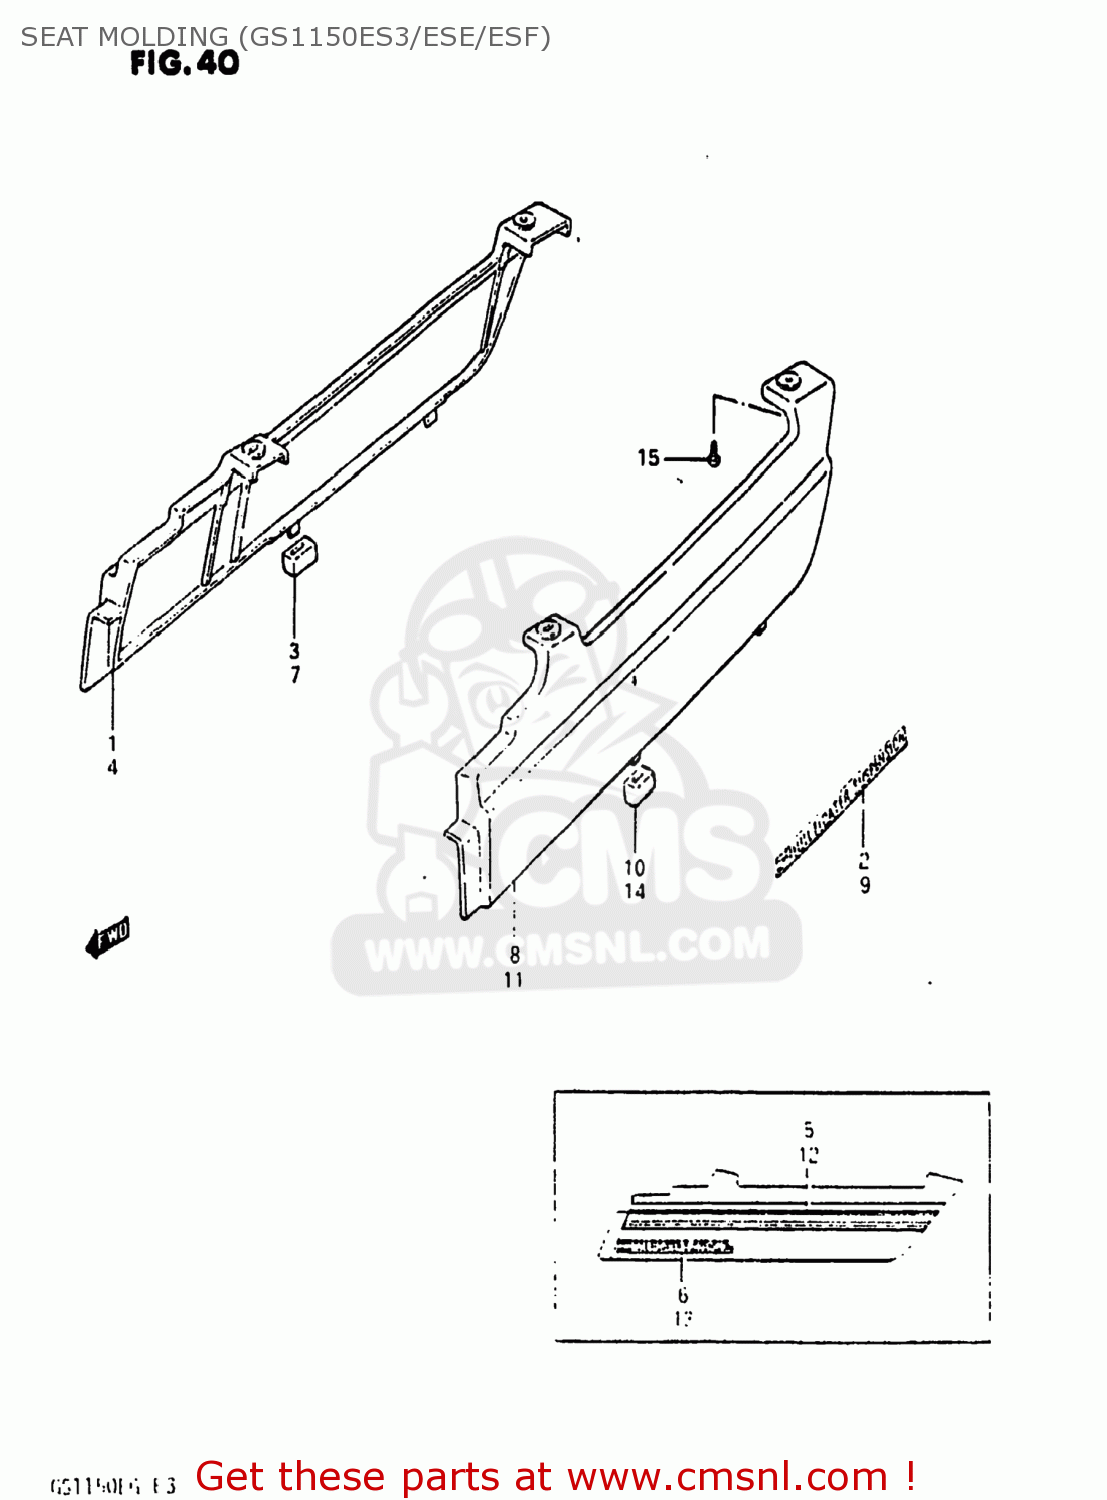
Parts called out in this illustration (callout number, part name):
1	MOLDING,SEAT,RIGHT
2	EMBLEM
3	CAP,SEAT MOLDING
4	MOLDING,SEAT,RIGHT
5	TAPE SET,SEAT MOULDING
6	EMBLEM
7	CAP,SEAT,MOLDING
8	MOLDING,SEAT,LEFT
9	EMBLEM
10	CAP,SEAT MOLDING
11	MOLDING,SEAT,LEFT
12	TAPE SET
13	EMBLEM
14	CAP,SEAT,MOLDING
15	SCREW
